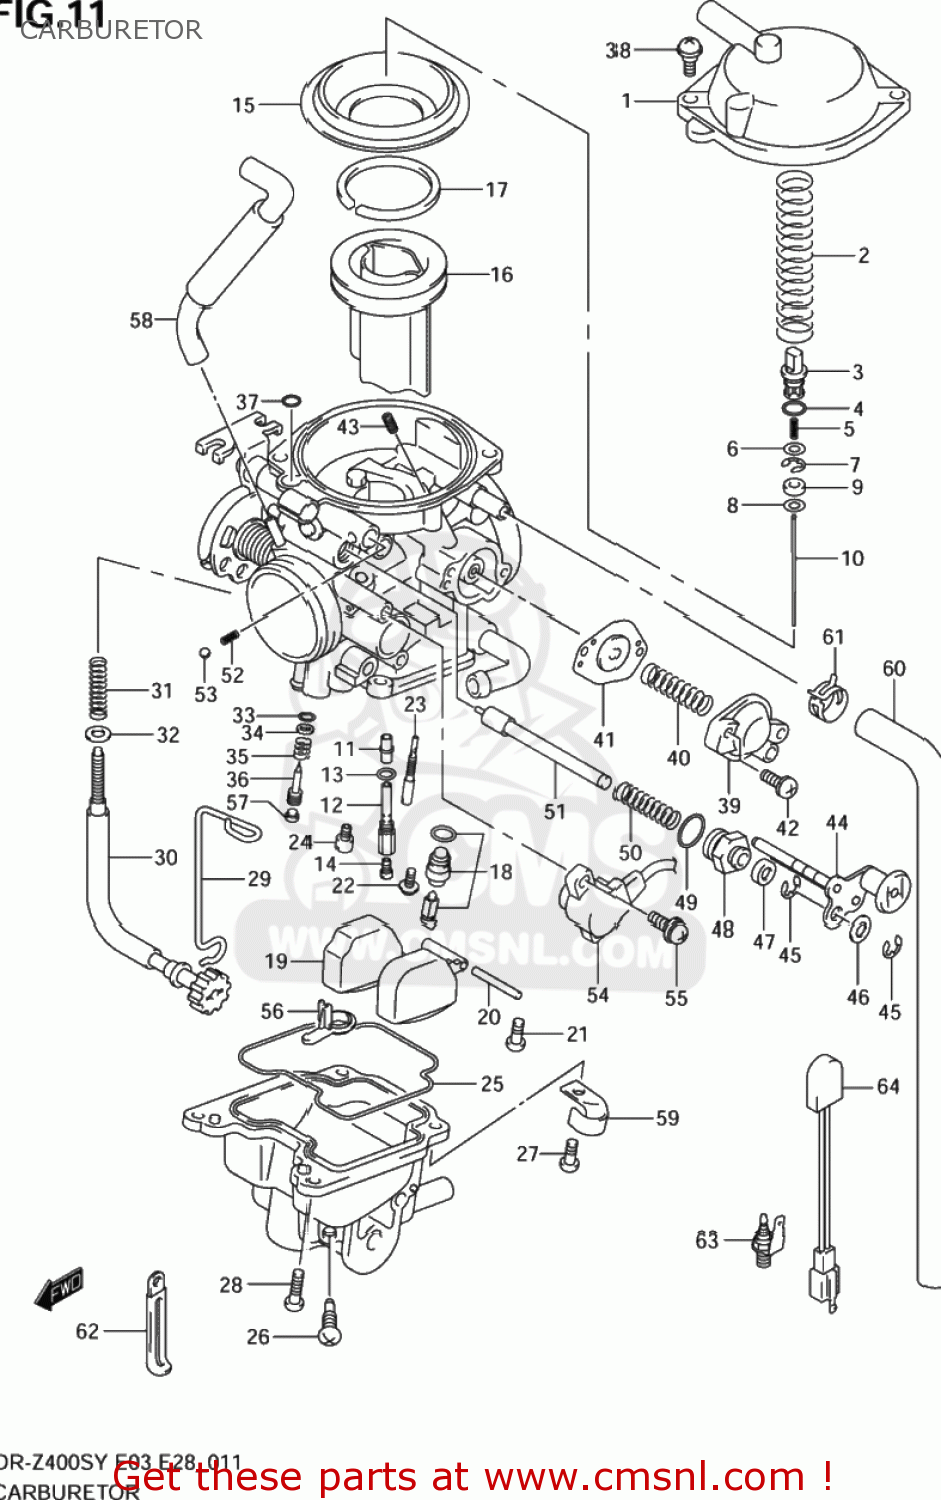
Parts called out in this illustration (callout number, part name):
1	COVER ASSY,DIAPHRAGM
2	SPRING
3	HOLDER
4	O RING(D:1.9,ID:4.8)
5	SPRING
6	WASHER
7	E RING,MULTIPLE JET NOZZLE
8	RING
9	WASHER
10	NEEDLE,JET
11	JET
12	HOLDER,JET
13	O RING
14	JET,MAIN(142.5)
15	DIAPHRAGM
16	VALVE,PISTON
17	RING
18	VALVE ASSY,NEEDLE
19	FLOAT ASSY
20	PIN,FLOAT
21	SCREW
22	SCREW
23	JET,PILOT(22.5)
24	JET,MAIN(62.5)
25	GASKET (NAS)
26	PLUG,DRAIN
27	SCREW
28	SCREW
29	CLIP
30	SCREW,ADJUST
31	SPRING,THROTTLE SCREW
32	WASHER,STARTER SHAFT
33	O RING,PILOT AIR SCREW
34	WASHER
35	SPRING,THROTTLE SCREW
36	ADJUSTER
37	O RING
38	SCREW
39	COVER ASSY
40	SPRING
41	DIAPHRAGM ASSY
42	SCREW
43	JET,POWER(135)
44	PLATE ASSY
45	E RING
46	WASHER
47	CAP,STARTER VALVE
48	GUIDE SCREW,PLUNGER
49	O RING
50	SPRING
51	PLUNGER ASSY
52	SPRING
53	BALL,CARBURETOR
54	SENSOR ASSY
55	SCREW
56	RING
57	PLUG
58	HOSE
59	PLATE
60	HOSE,AIR VENT(6.5X10.5)
61	CLIP
62	CLAMP(L:65)
63	HEATER ASSY,CARBURETOR(15W)
64	THERMO SWITCH,CARB HEATER
